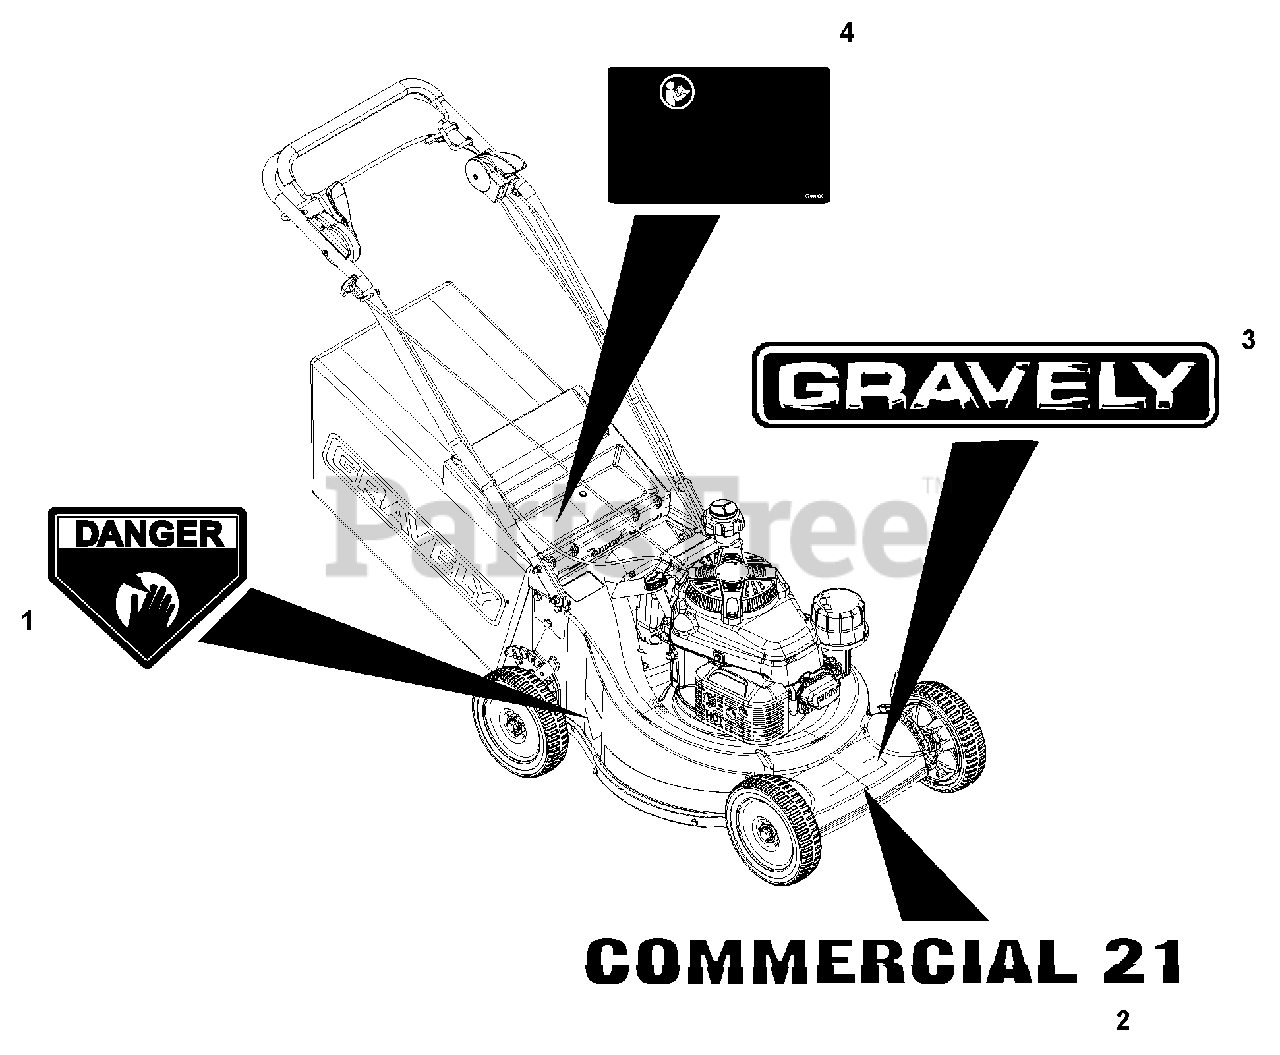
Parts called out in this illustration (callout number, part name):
1	Decal, Danger
2	Decal, Style, Commercial LM
3	Decal, 6.5" Gravely Logo
4	Decal, Main Safety, Commercial LM
